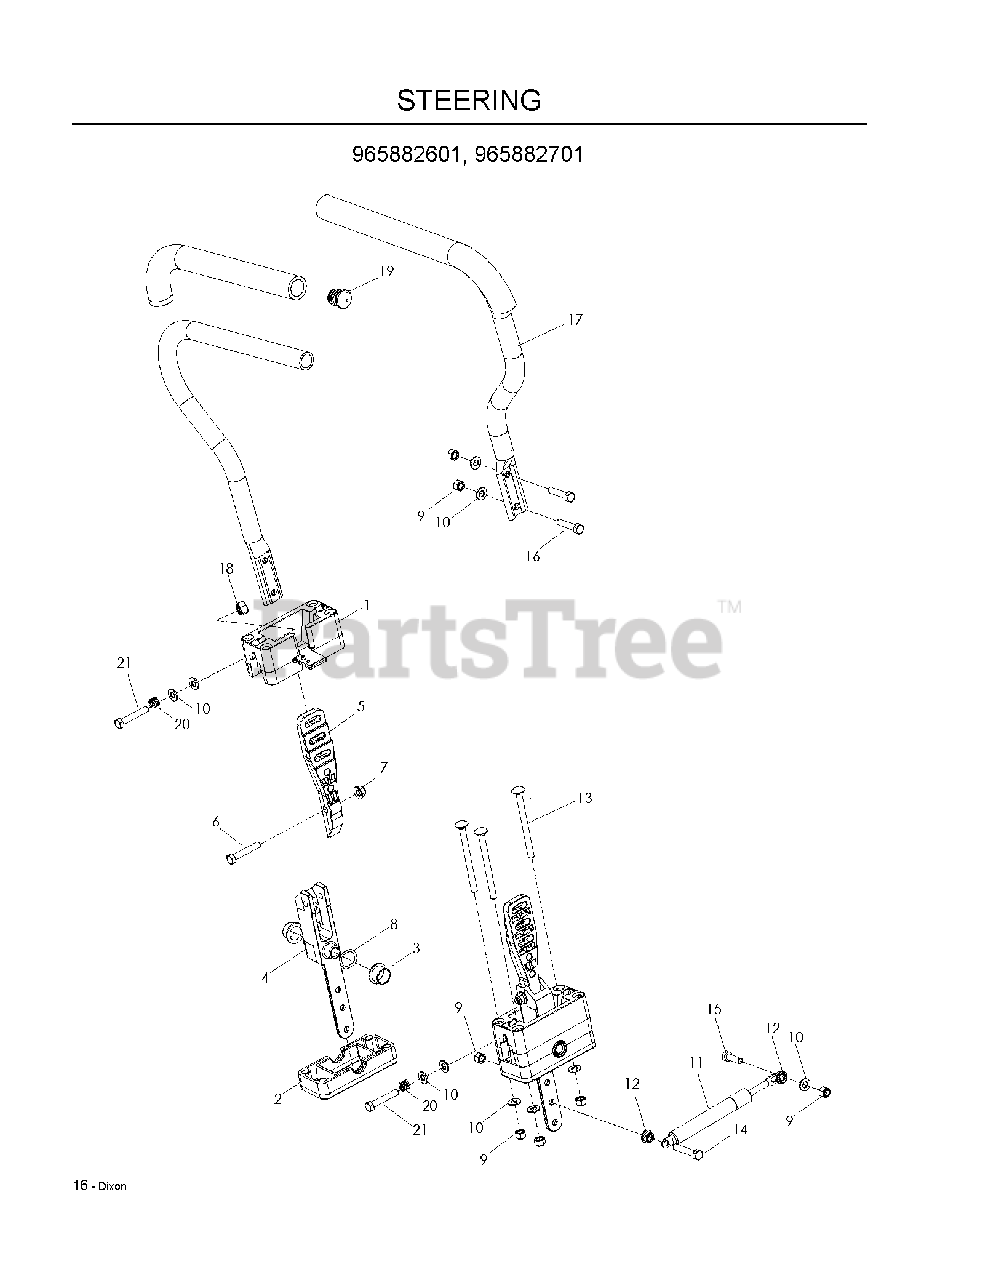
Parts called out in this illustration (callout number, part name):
1	BLOCK, UPPER
2	BLOCK, LOWER
3	BEARING, FLANGE
4	PIVOT.SECTION.DRIVE.CONTROL
5	MOUNT, DR CNTRL HANDLE
6	HCS 5/16C X 1 3/4
7	5/16-18 NYLOC FLANGE NUT
8	WASHER, .825 X 1.087, WAVE
9	NUT 5/16 NYLOC
10	FLAT WASHER 5/16 SAE
11	DAMPENER
12	NUT 5/16C WHIZ
13	RHSNB 5/16-18 X 4 GR 5 ZD
14	HCS 5/16-18X1-3/4 TPBLT
15	HCS 5/16C X 1
16	CAPSCREW 5/16 X 1/1/2 HEX HEAD
17	LEVER.DRIVE.W/GRIP
18	NUT 5/16C HEX
19	END PLUG 15/16` (BLACK)
21	HCS 5/16-18 X 2 TPBLT GR 5 ZD
22	GRIP, FOAM (GROUND) 15
